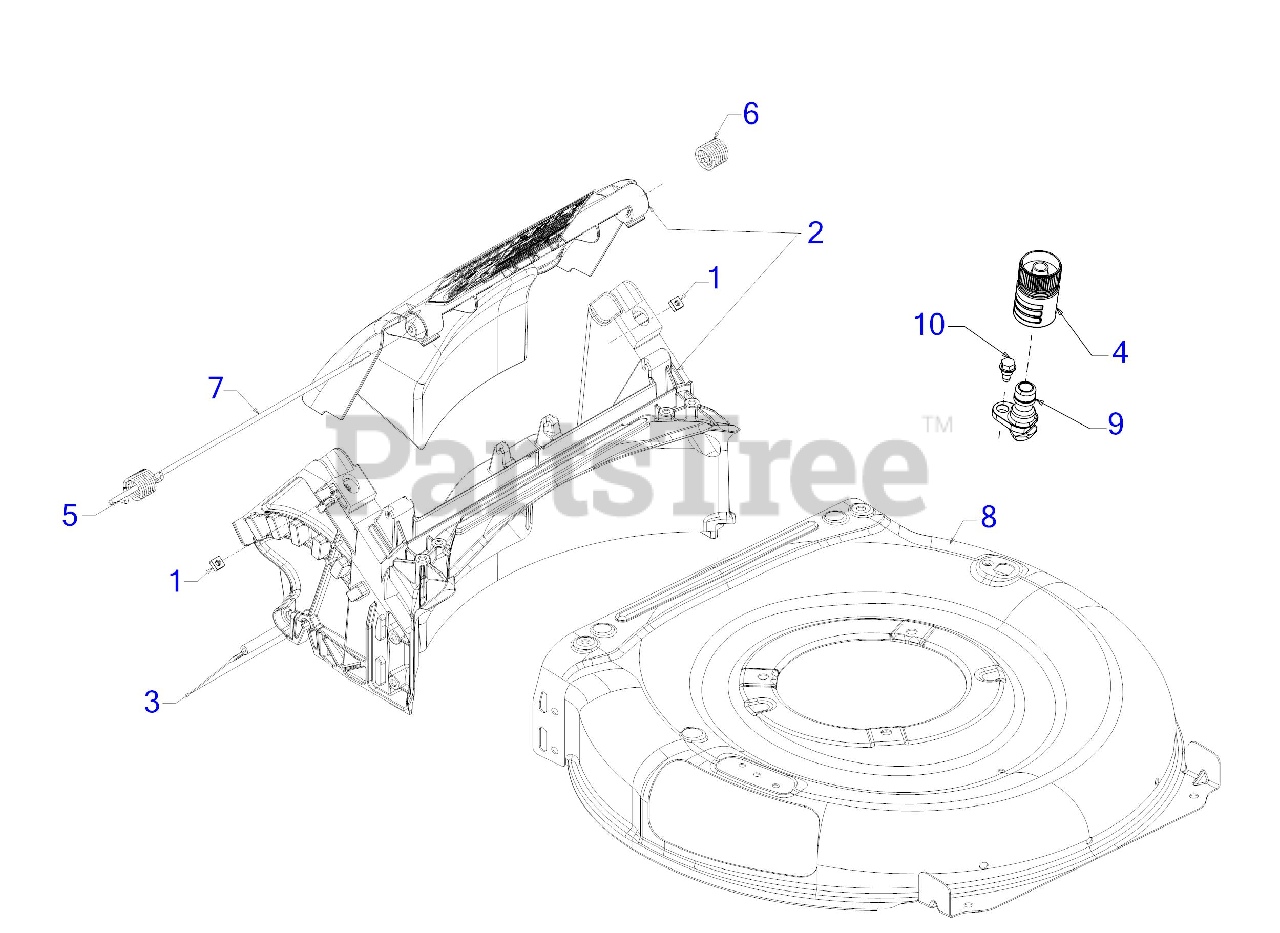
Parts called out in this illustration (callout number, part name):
1	SQUARE NUT 1/4-20
2	DOOR ASSEMBLY
3	TRAILSHIELD
4	WATER NOZZLE
5	TORSION SPRING (RH)
6	TORSION SPRING (LH)
7	REAR DOOR PIVOT ROD
9	DECK WASH NOZZLE
10	SHOULDER SCREW 1/4-20 x .50
